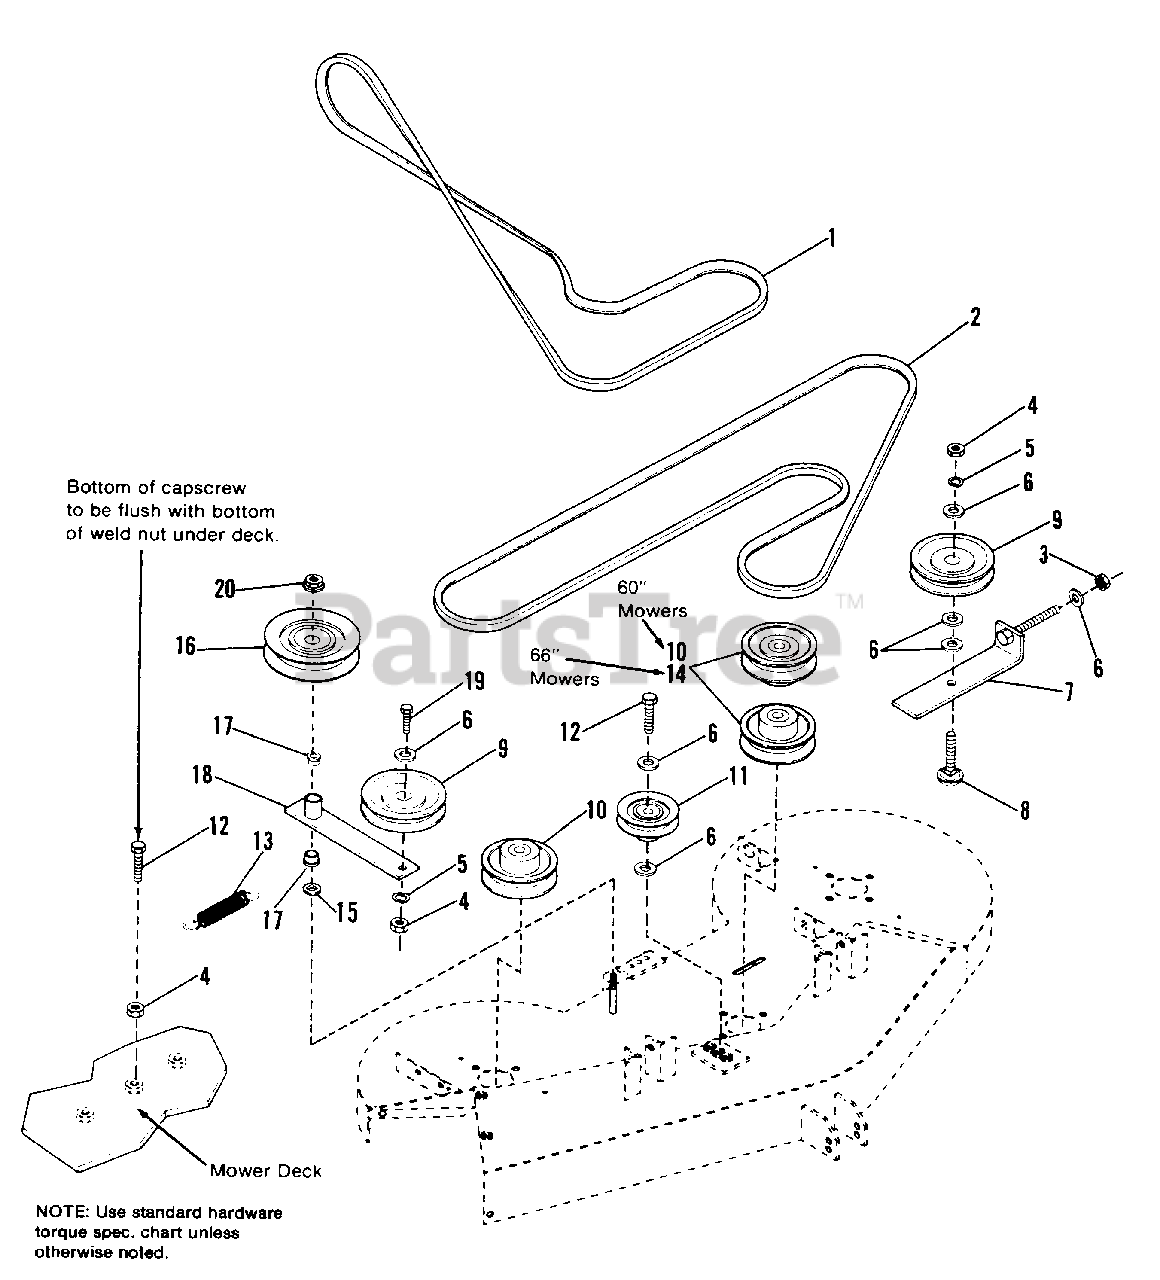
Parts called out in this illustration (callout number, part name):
1	V-BELT, Mower
2	V-BELT, Mower (60" Mower)
2	V-BELT, Mower (66" Mower)
3	LOCKNUT, Fiber, 3/8-16
4	NUT, Hex, 3/8-16
5	LOCKWASHER, Spring, 3/8
6	WASHER, Plain
7	DRAW BRACKET ASSY.
8	CARRIAGE BOLT, 3/8-16 x 2
9	PULLEY, Idler, Backside, 4" dia.
10	V-PULLEY, Drive (60" Mower) V-PULLEY, Drive (66" Mower)
11	V-PULLEY, Idler, 4" dia.
12	CAPSCREW, Hex, 3/8-16 x 1-3/4
13	SPRING, Extension
14	V-PULLEY, Drive (66" Mower only)
15	WASHER, Plain
16	V-PULLEY, Idler
17	BEARING, Nylon, Flanged
18	IDLER ARM ASSY.
19	CAPSCREW, Hex, 3/8-16 x 2-1/2
20	NUT, Lock, Hex, Flanged, 3/8-16
